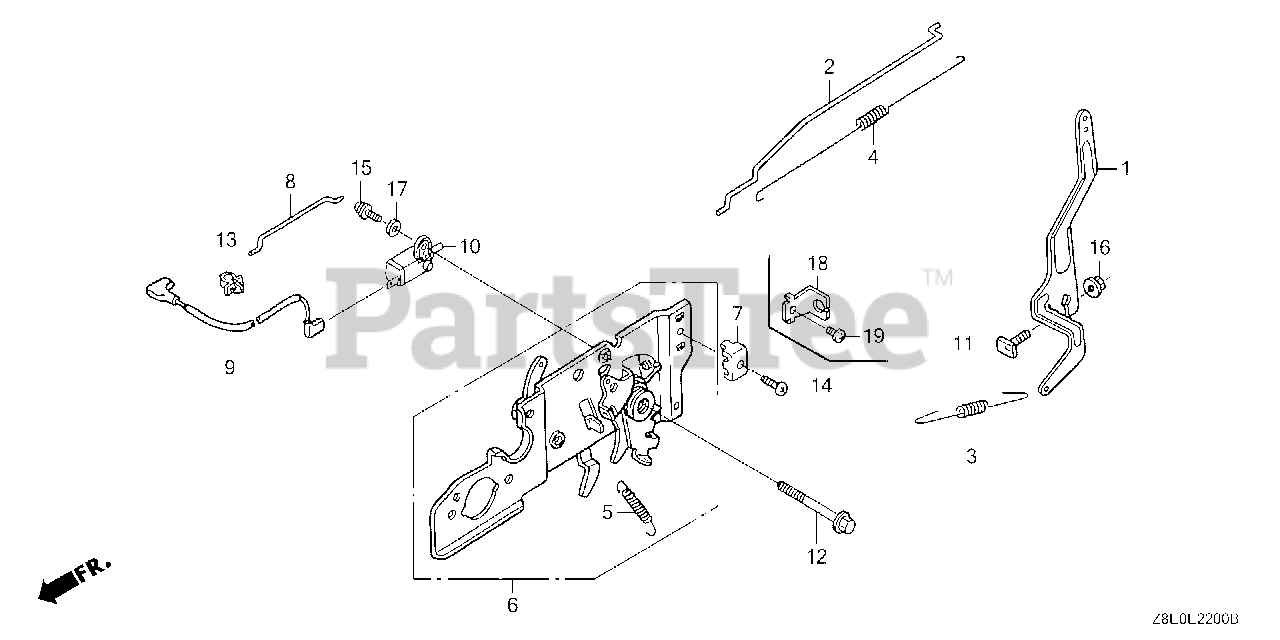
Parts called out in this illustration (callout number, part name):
1	ARM, GOVERNOR
2	ROD, GOVERNOR
3	SPRING, GOVERNOR
4	SPRING, THROTTLE RETURN
5	SPRING, LEVER
6	BASE, CONTROL
8	ROD, CHOKE
9	WIRE, STOP SWITCH
10	SWITCH ASSY., ENGINE STOP (N.O)
11	BOLT, GOVERNOR ARM
12	BOLT, FLANGE (6X50)
13	HOLDER, WIRE (FASTEX)
15	SCREW-WASHER (4X12)
16	NUT, FLANGE (6MM)
17	WASHER, PLAIN (4MM)
18	HOLDER, CABLE
19	SCREW, PAN (5X8)
